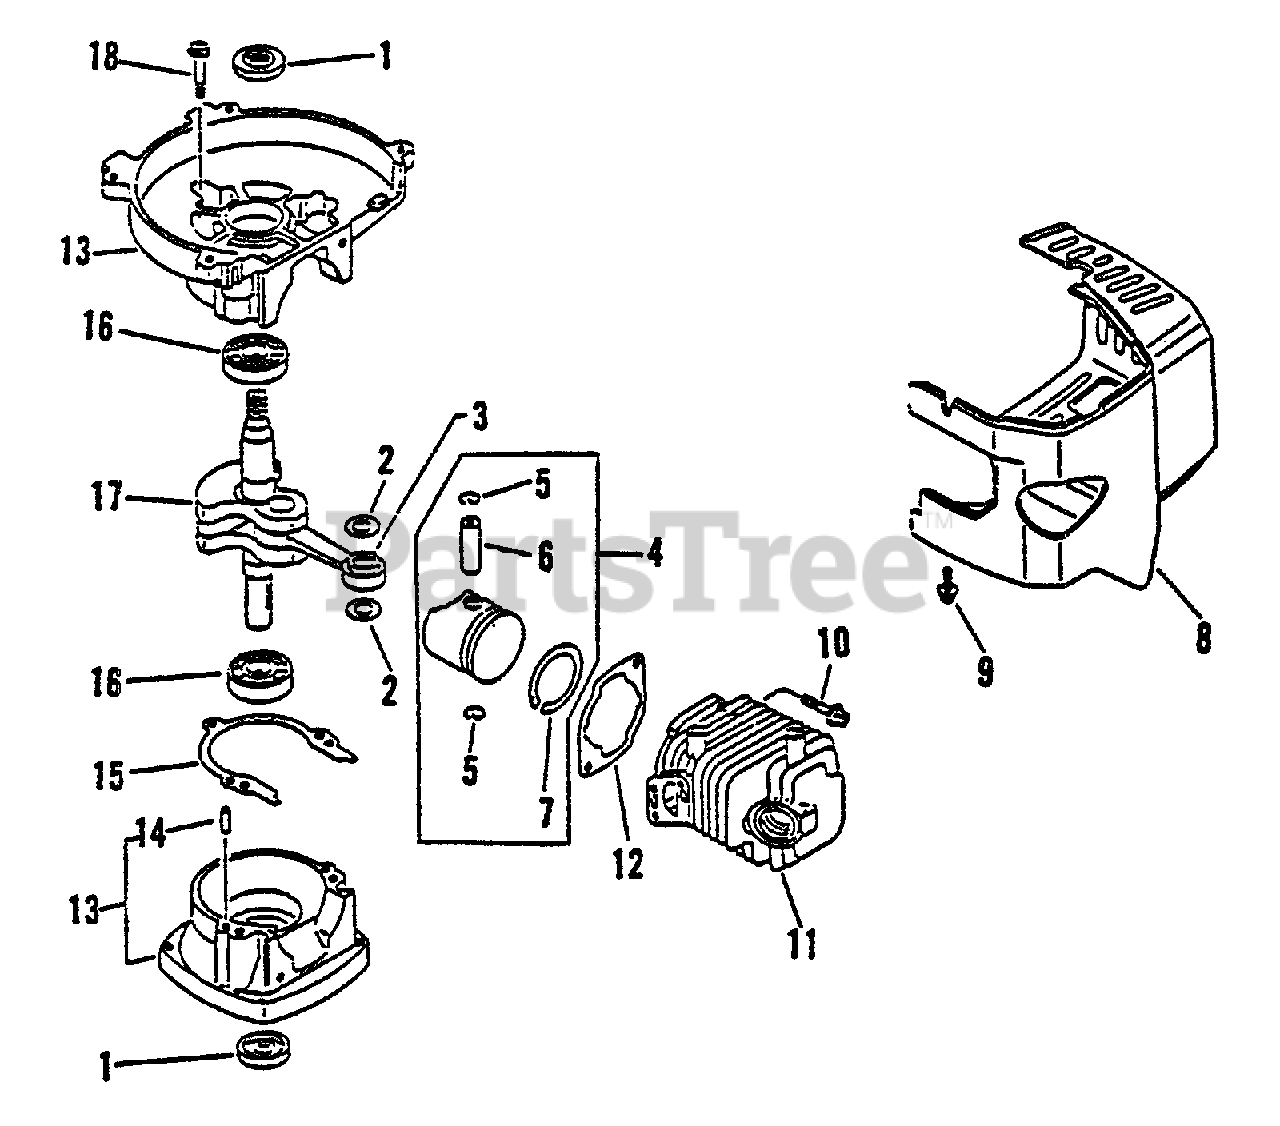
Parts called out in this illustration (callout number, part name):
1	SEAL, OIL
2	SPACER, PISTON
3	BEARING, NEEDLE
4	PISTON KIT
5	RING, RETAINING
6	PIN, PISTON
7	RING, PISTON
8	COVER, ENGINE
9	SCREW - 4X20
10	SCREW - 5X22
11	CYLINDER
12	GASKET, CYLINDER
13	CRANKCASE KIT
14	PIN - LOCATING
15	GASKET, CRANKCASE
16	BEARING, BALL - 6201
17	CRANKSHAFT ASSY
18	SCREW - 5X28
